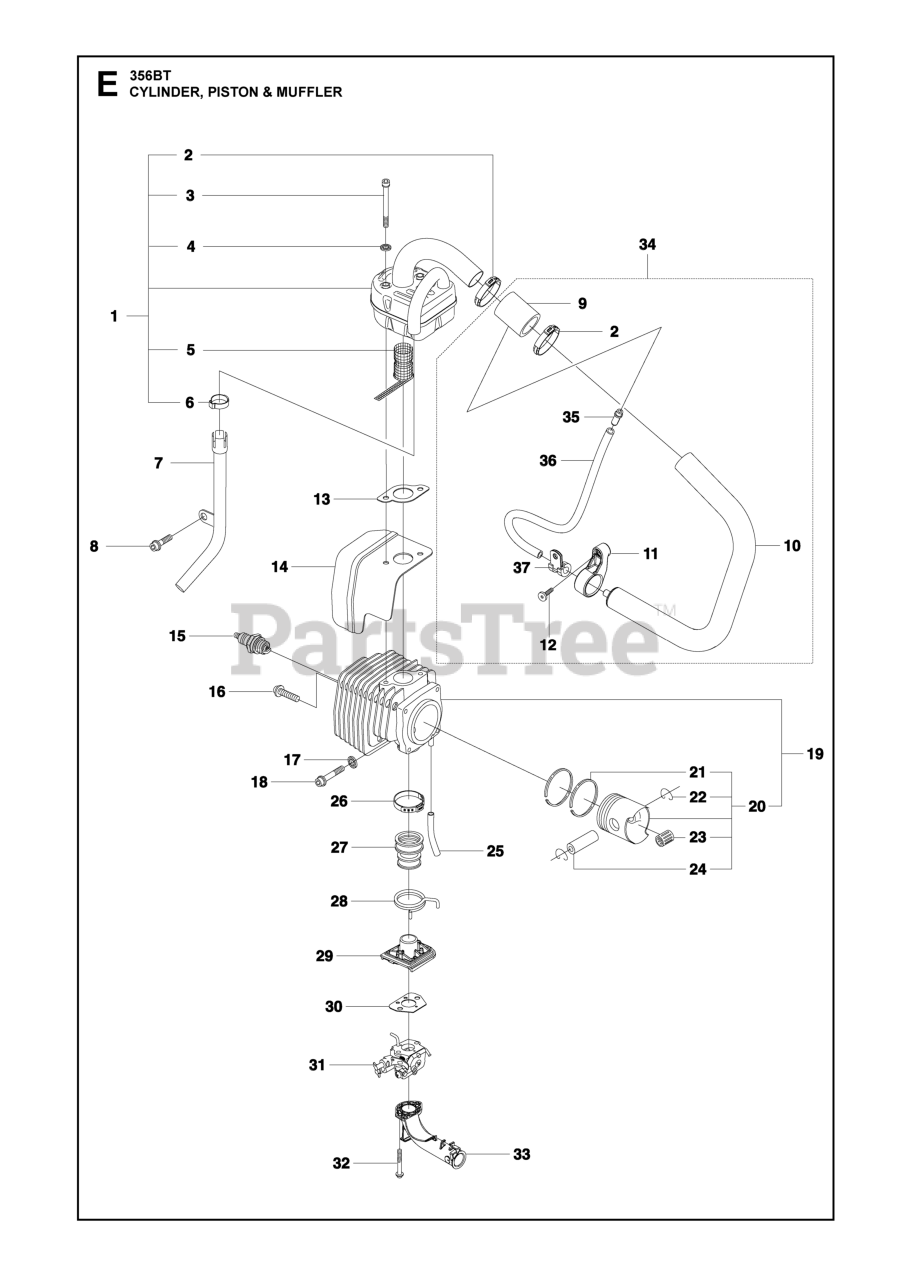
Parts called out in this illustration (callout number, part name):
4	DOUBLE WASHER
5	SPARK ARRESTOR
9	HOSE
10	PIPE COMPLETE BLAIR TUBE
12	SCREW M5X14
15	SPARK PLUG RCJ7Y
16	SCREW MC6S 5X25
17	DOUBLE WASHER
20	PISTON CPL 44MM
21	PISTON RING
22	WRIST PIN CLIP
23	BEARING
24	PISTON BOLT
27	INLET TUBE
31	CARBURETOR
33	INLET BEND 5MM WIRE
34	PIPE COMPLETE BLAIR TUBE
